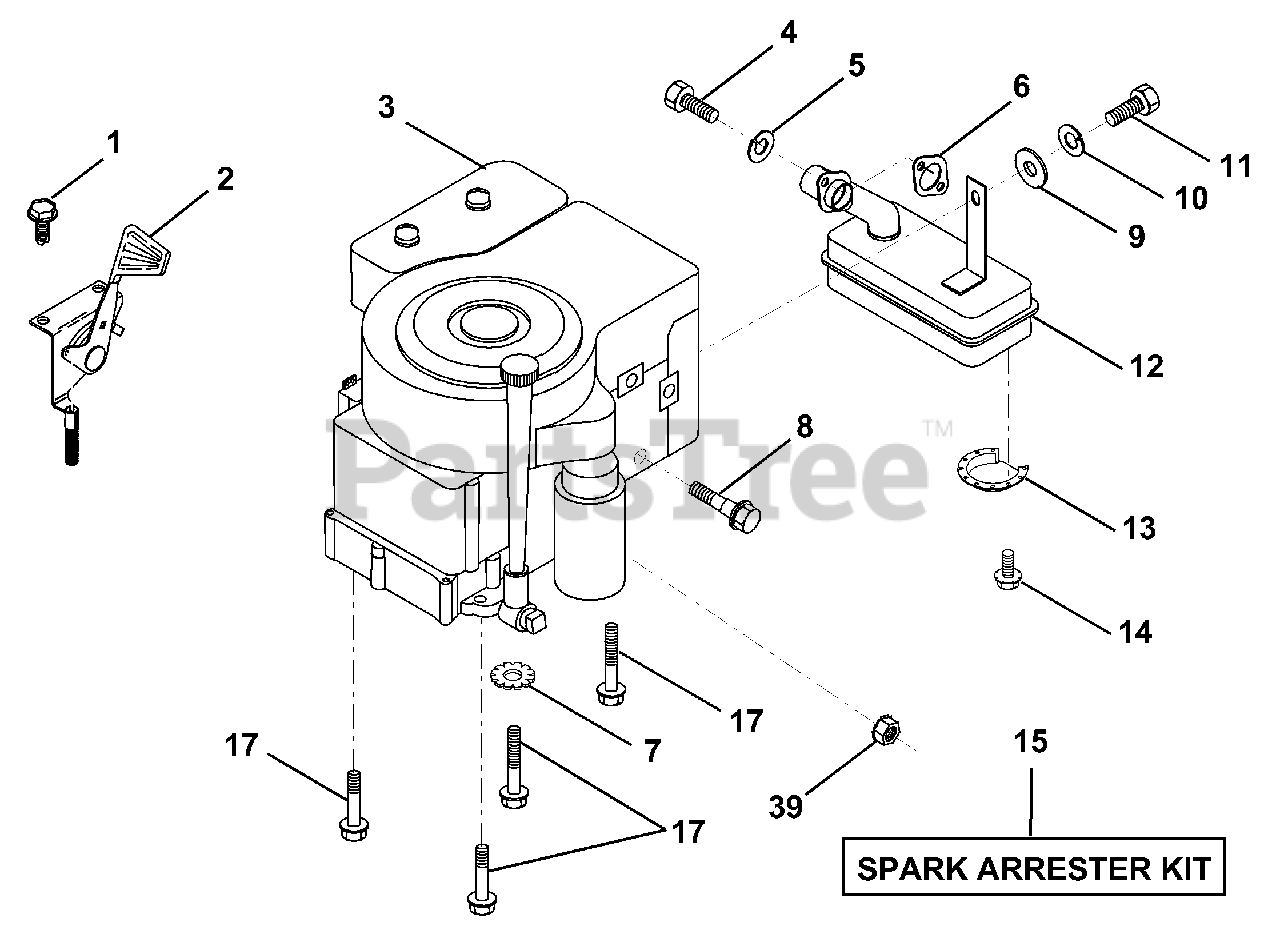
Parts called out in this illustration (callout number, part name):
1	Screw, Hex Thd. Cut 1/4-20 x 1/2
2	Control, Throttle
4	Screw, Hex, Cap 5/16-18 x 3/4
5	Washer, Lock Hvy Hcl Spring 5/16
6	Gasket, Exhaust
7	Washer Lock Ext. Tooth 3/8
8	Bolt, Shoulder 5/16
9	Washer 5/16 x 3/4 x 16
10	Washer, Lock Hvy Hlcl Spring 1/4
11	Bolt, Hex Fin.
13	Deflector, Muffler
14	Screw, Spiderlock, Hex Hd 8 x 1/2
15	Arrester, Spark
17	Screw, Hex Washer Head, Thdrol. 3/8-16 x 1-1/2
39	Nut, Flange 1/4-20
